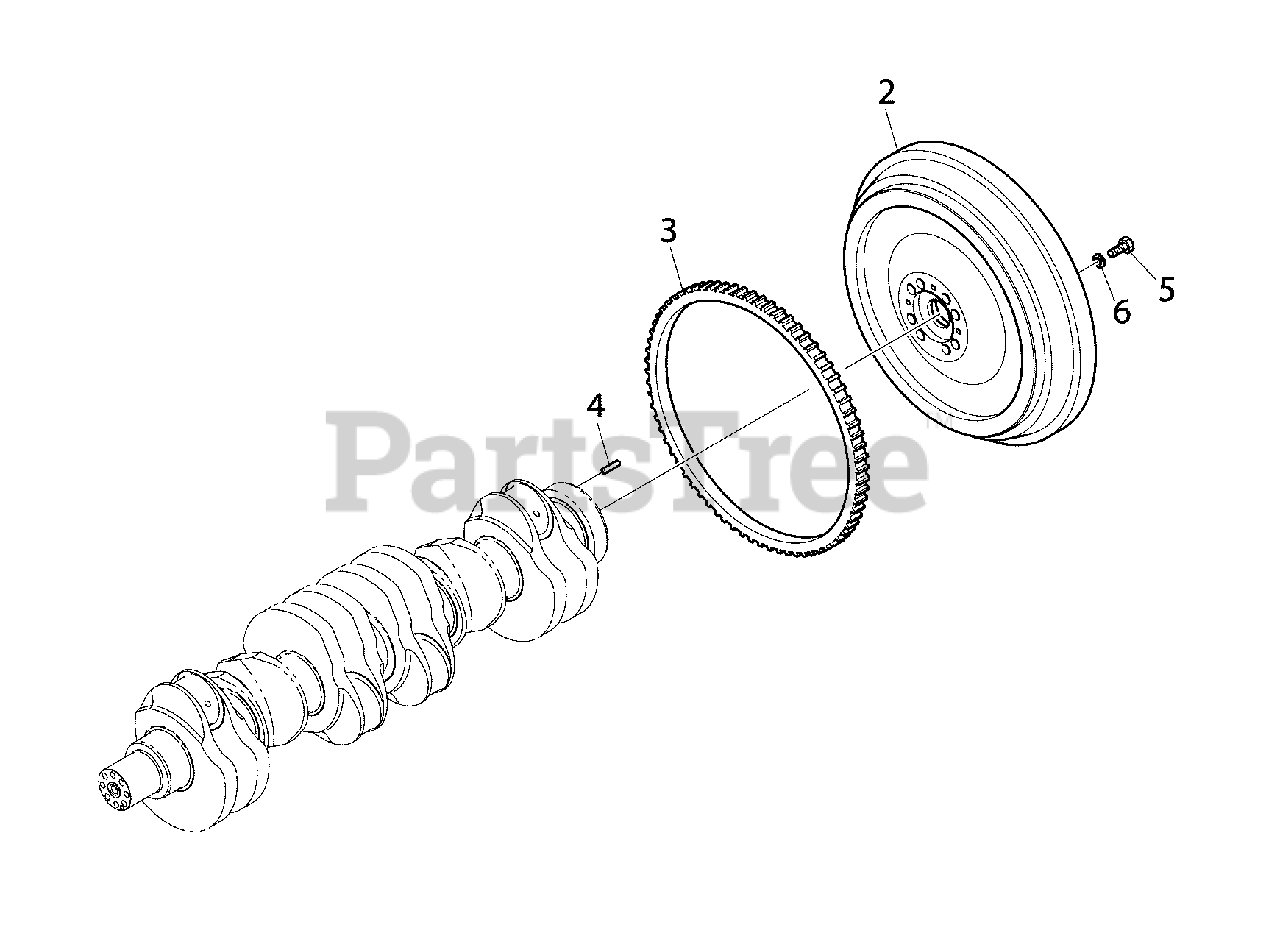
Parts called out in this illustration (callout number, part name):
2	* FLYWHEEL
3	* GEAR, RING
4	* PIN, DOWELL
5	* BOLT, HEX
6	* WASHER, SPRING
